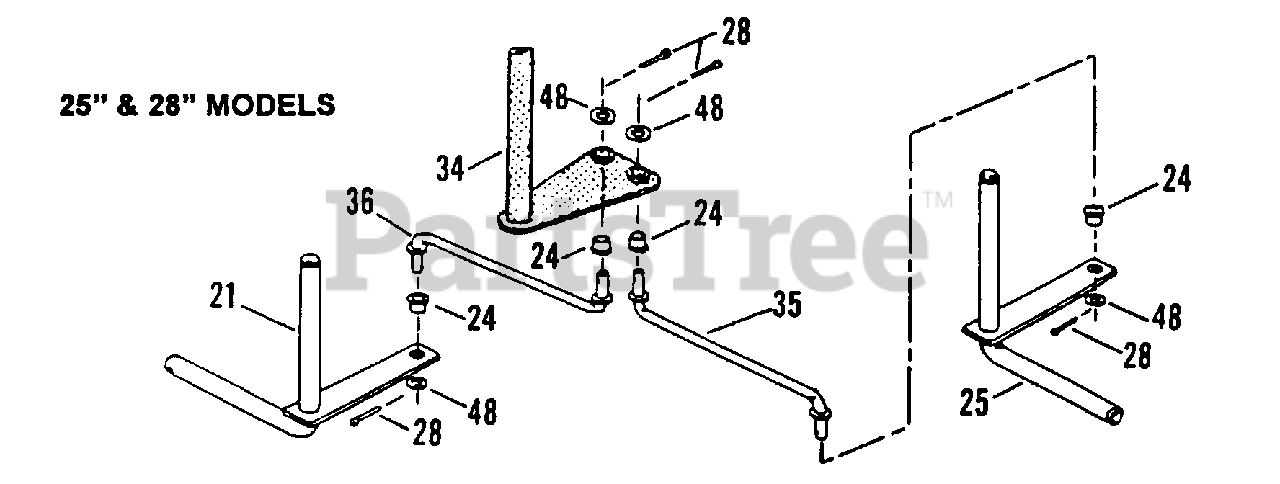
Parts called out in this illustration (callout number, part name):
21	PIN, Narrow King (Right Side)
24	BUSHING
25	PIN, Narrow King (Left Side)
28	PIN, 5/32 x 1" Cotter
34	SHAFT, Steering (Narrow Front End)
35	TIE-ROD, Left Side
36	TIE-ROD, Right Side
48	WASHER, 3/8" Flat
